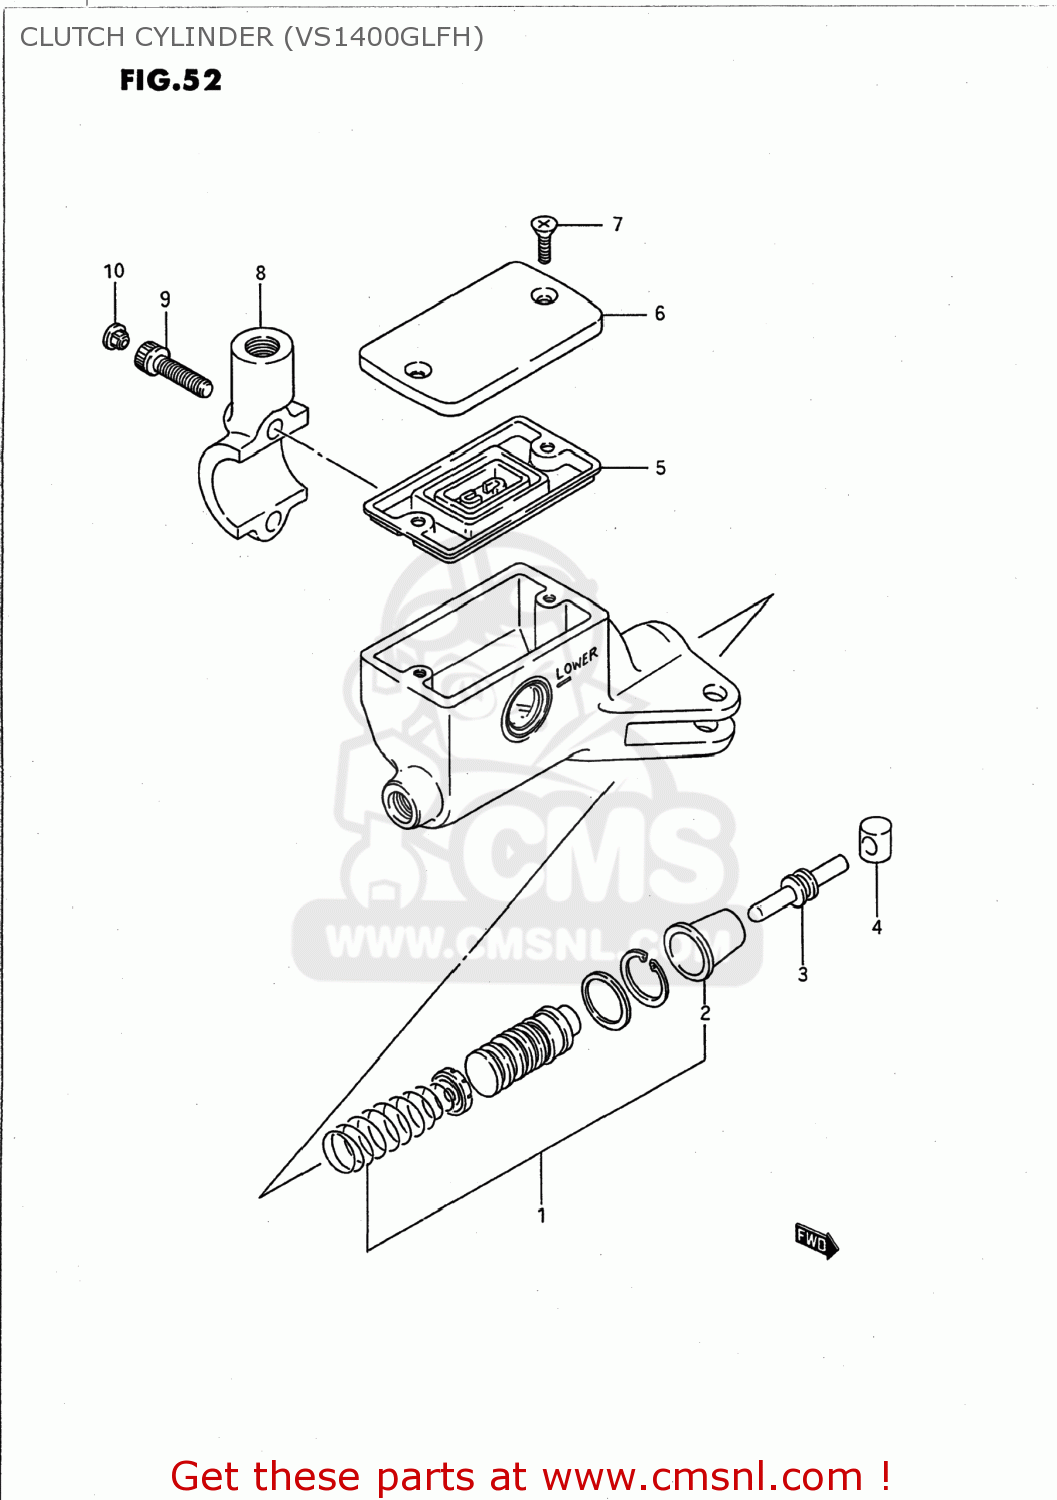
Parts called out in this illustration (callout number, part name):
1	PISTON & CUP SET
2	BOOT
3	PUSH ROD
4	BUSH
5	6
6	CAP
7	SCREW,RESERVOIR CAP
8	HOLDER
9	BOLT ,6X20
10	CAP(OD:10)
